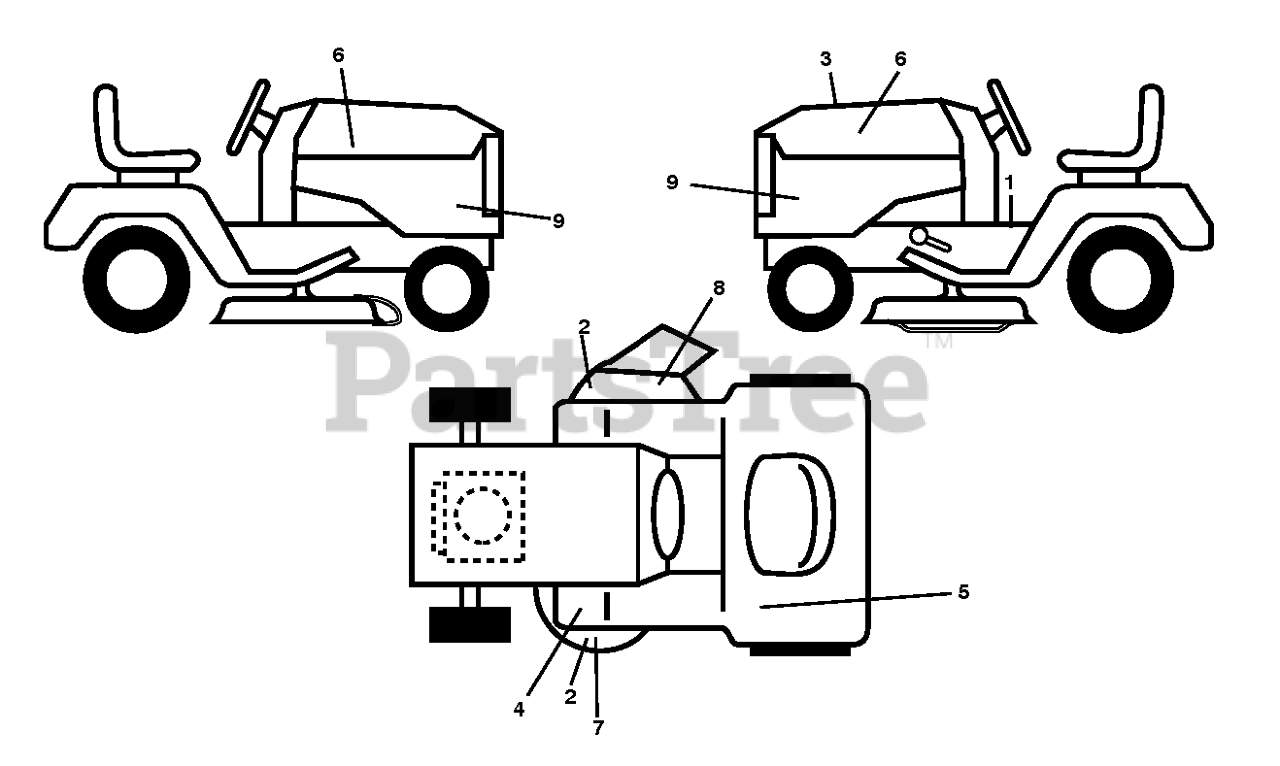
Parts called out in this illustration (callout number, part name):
1	DECAL.TRACTOR.SADDLE
3	DECAL.RPL.KAW730V-ES04.54.K66
4	DECAL BELT ROUTING DECAL DECAL
6	DECAL.BADGE.170MM.TEXTLOGO.
7	DECAL.54DECK.CLEARCUT.VER2.18
8	DECAL.TRACT/ZTR.DECKWARN.HUSQ
